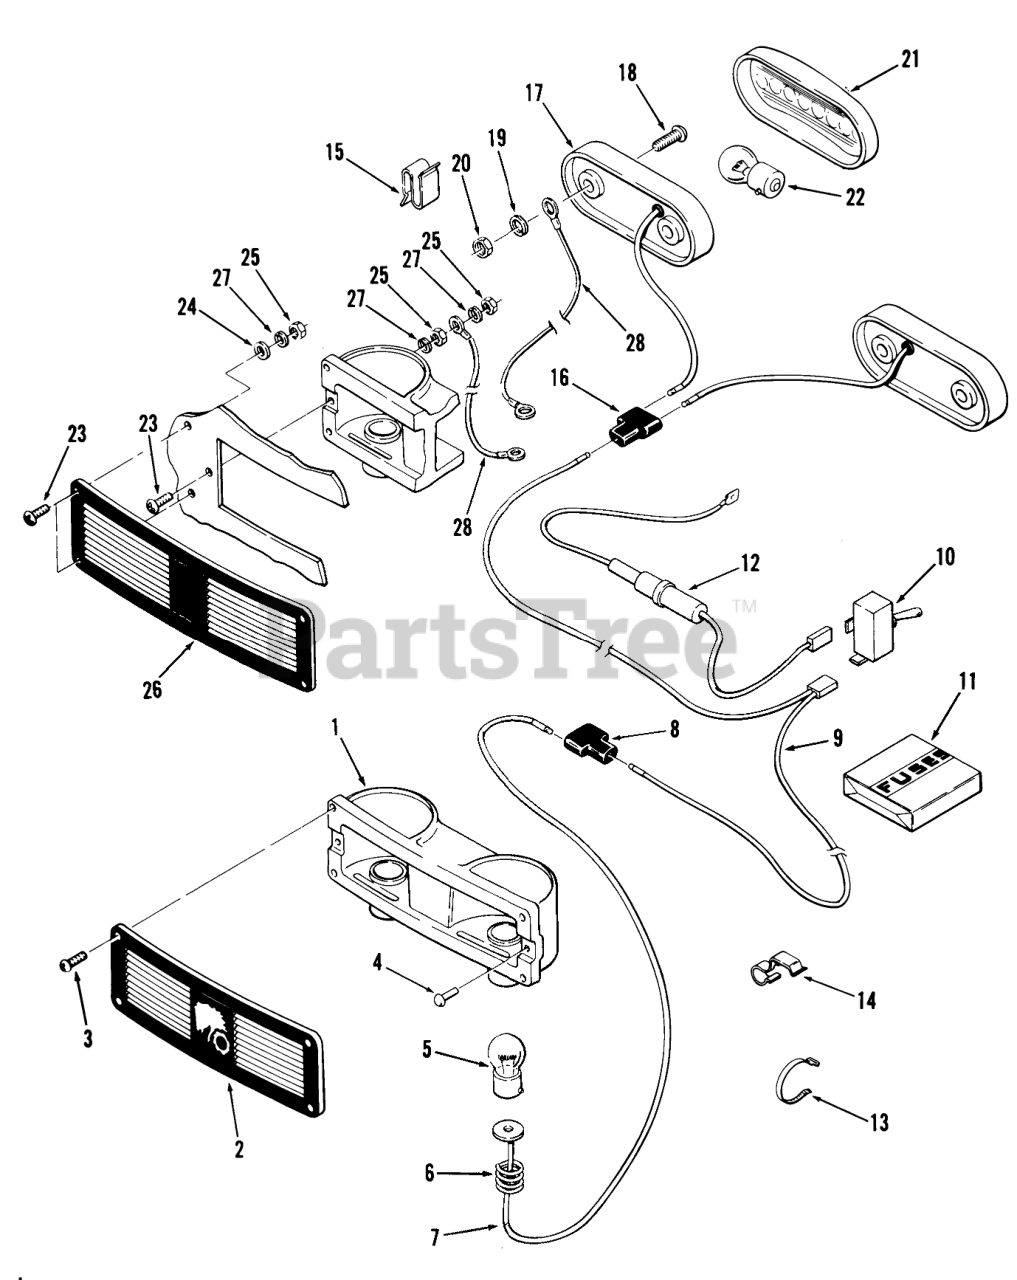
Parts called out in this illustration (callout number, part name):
5	BULB
6	SPRING
10	SWITCH-LIGHTS
22	Bulb
